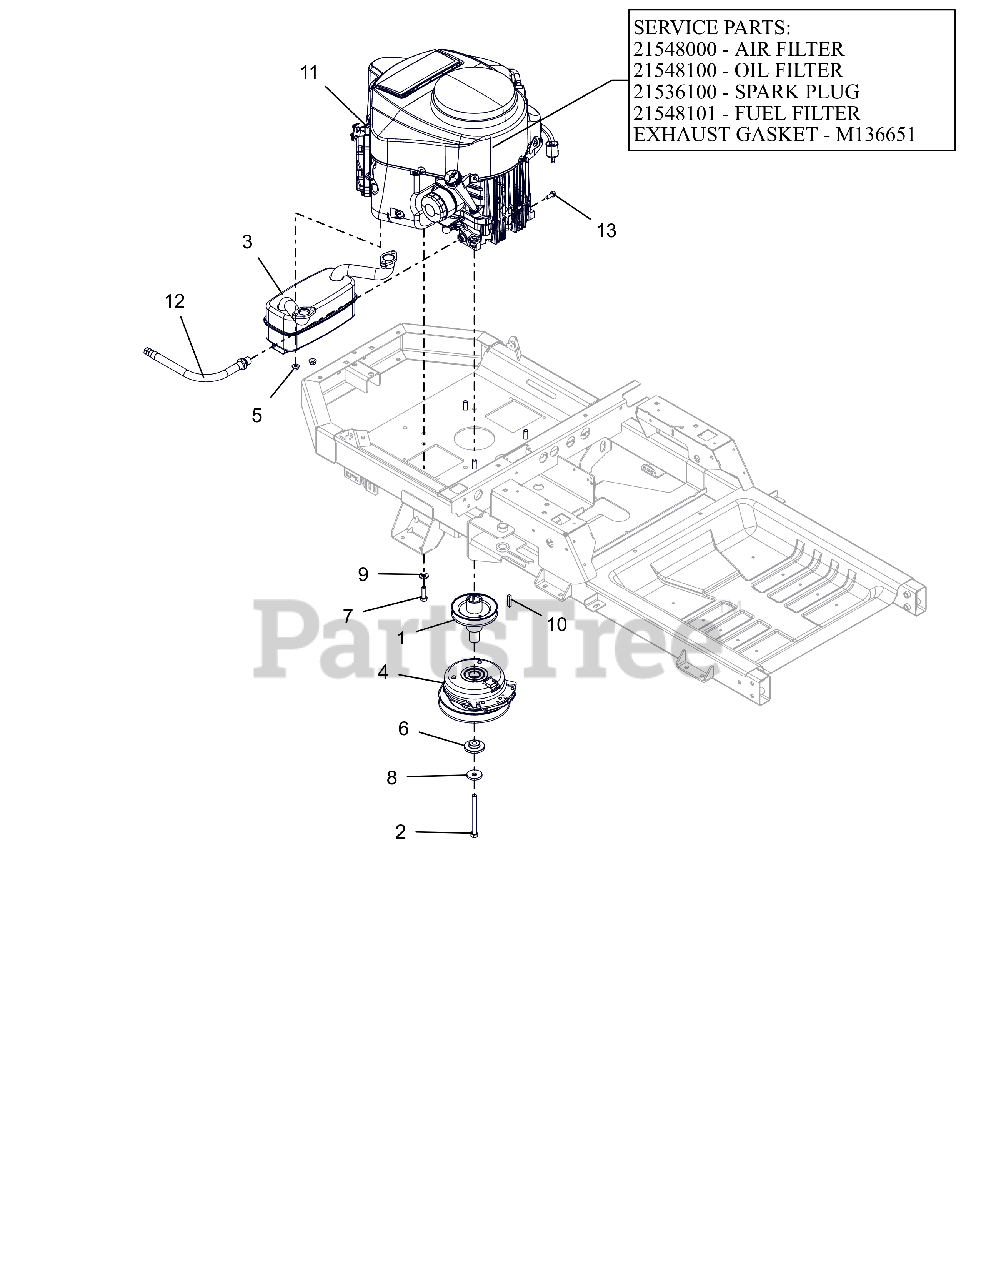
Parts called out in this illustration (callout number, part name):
1	WLDMT, DRIVE SHEAVE-X
2	BLT, HEX .44-20X4.50 G8 ZCC NT
3	MUFFLER, KAWASAKI
4	CLUTCH,105FTLB MONOPOLE 6.83"
5	NUT-LK-TOP-FLG M8 ZCC
6	BSHG-FLG .469X1.06X.574X2.0
7	BLT, HEX .38-16X1.25 G5 ZCC NT
8	WASHER, 7/16" SPRING DISK
9	WASHER, 3/8" SPRING DISC
10	KEY-SQ .25 X 1.25 X .25 SAE
11	ENGINE, KAWASAKI FR691 23HP
11	AIR FILTER, KAWASAKI FR
11	OIL FILTER, KAWASAKI FR
11	PLUG, SPARK
11	FUEL FILTER-KAWASAKI FR
11	GASKET, MUFFLER #
12	HOSE, OIL DRAIN
13	BLT, HEX M8-1.25X20 G8.8 ZCC
